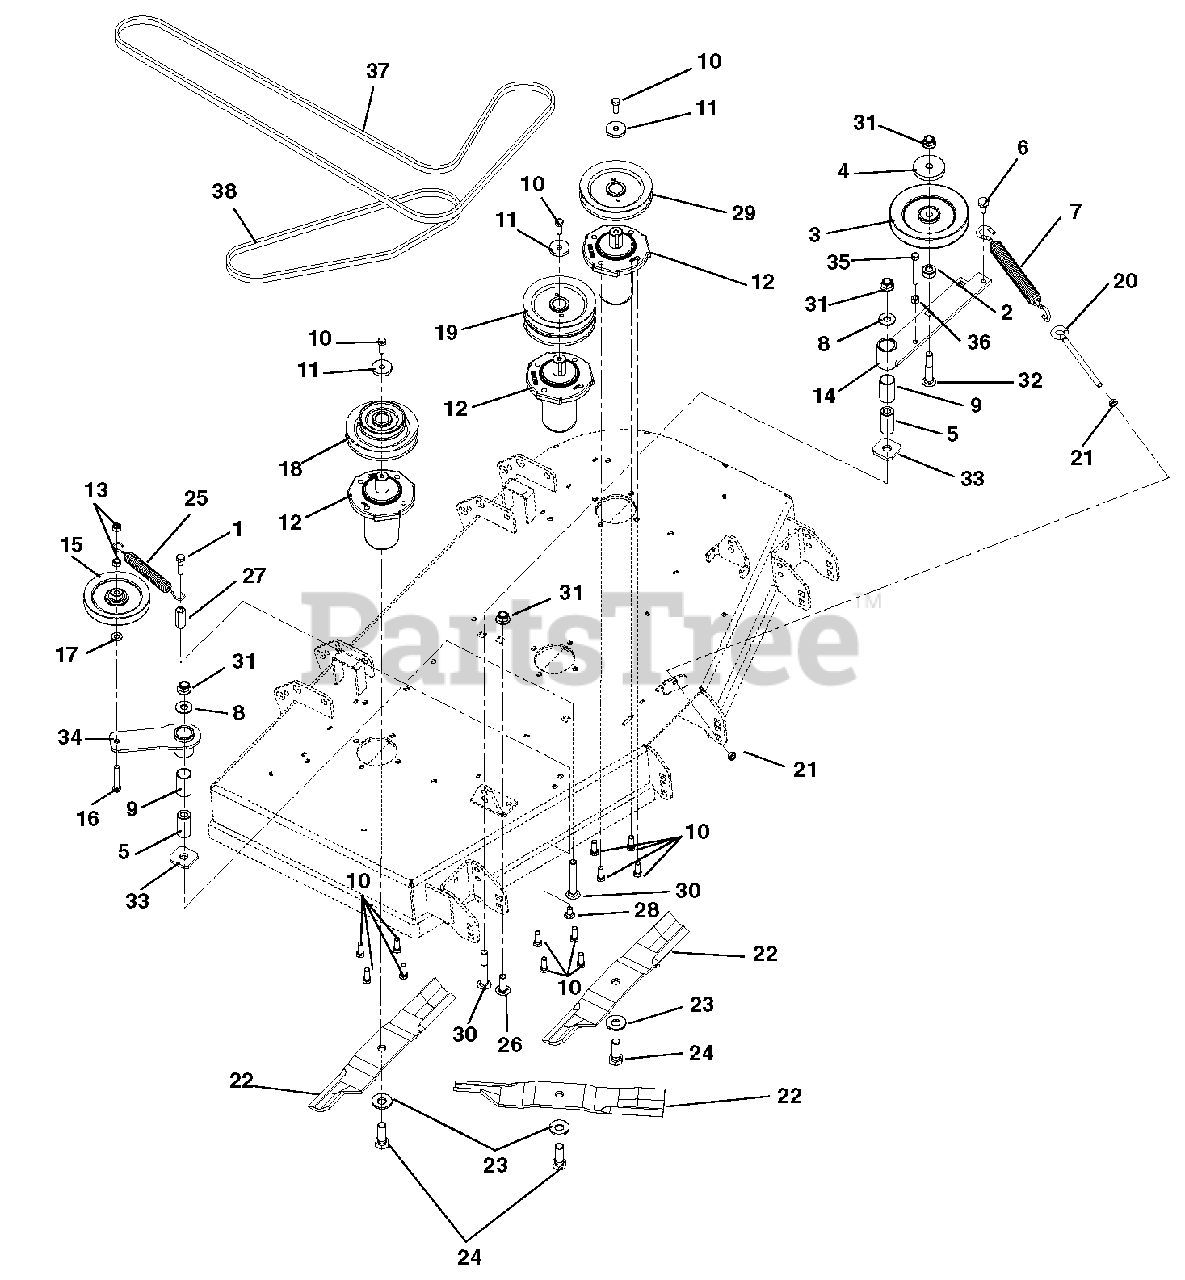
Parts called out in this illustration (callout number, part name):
1	Bolt, Hex .38-16 x 1.75 Grade 5
2	Bushing, Spacer .502 x .997 x .50
3	Sheave, .50"ID x 6.00"OD V-Idlerg
4	Cap, Idler Bearing Sealing
5	Bushing, Spacer .505/.500 x .999/.996 x 2.05/2.03
6	Bolt, Shoulder EP .38-16 x .30 Hex
7	Spring, Extension (Deck Idler)
8	Washer, Flat Steel .563 x 1.38 x .109
9	Bushing, 1.00 x 1.125 x 1.936
10	Bolt, Hex .38-16 x 1.00
11	Washer, Flat Steel .406 x 1.50 x .245
12	Spindle Assembly
13	Nut, Locking-Center .38-16
14	Weldment, Idler Arm
15	Sheave, .38" ID x 5.00" OD V-Idler
16	Bolt, Hex .38-16 x 2.25
17	Washer, Flat Steel .406 x .812 x .065
18	Sheave, 44-48 Bagger Drive
19	Sheave, Double 1.0" ID x 5.50" OD
20	Bolt, .38-16 x 5.50 .62 Diameter Eye
21	Nut, Hex, Jam .375-16
22	Blade, 16.25 Mlch
23	Washer, Bellville .63 x 1.625 x.14
24	Bolt, Hex .62-18 x 1.75 Grade 8 (Torque to 115-125 ft. lbs.)
25	Spring, Extension
26	Bolt, Round Head Square Neck .50-13 x 1.5, Full Thread, Grade 5
27	Nut, Coupling .375-16 x 1.75
28	Bolt, Round Head Square Neck .38-16 x 1.00
29	Sheave, Single 1.0" ID x 5.50" OD
30	Bolt, Round Head Square Neck .50-13 x 3.50
31	Nut, .50-13 Nyloc Flange
32	Bolt, Round Head Square Neck .50-13 x 3.00 Grade 5
33	Washer, Flat .640 x 1.75 x .250
34	Weldment, Idler Arm
35	Bolt, Hex .38-16 x 2.75 Grade 5
36	Nut, Hex .38-16
37	Belt, BB 118.00 Wrapped Hex
38	Belt, B 51.18 Raw Cogged
